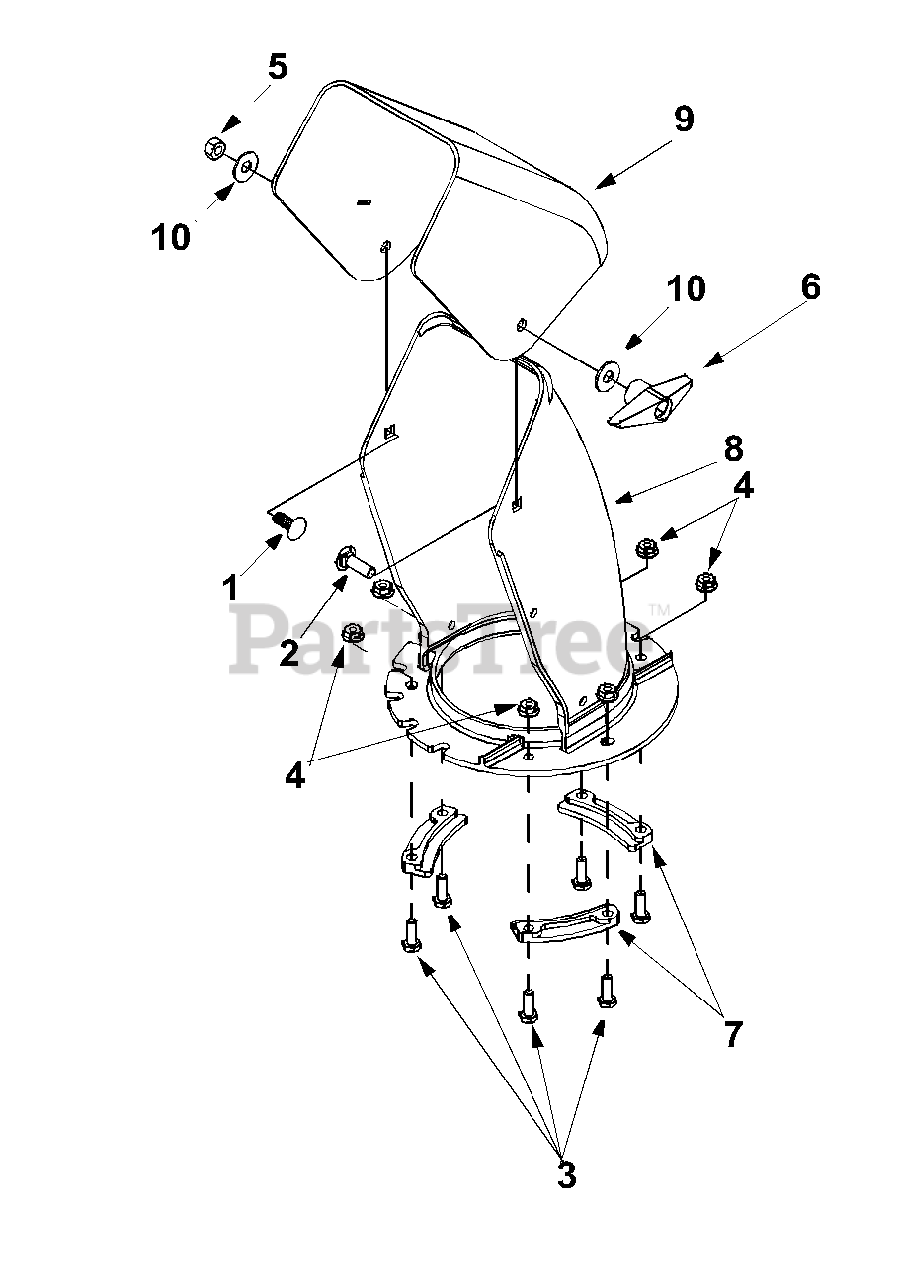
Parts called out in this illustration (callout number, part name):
1	Carriage Screw: Special
2	Carr. Bolt 5/16-18 x 0.750"
3	Hex Screw 1/4-20 x 0.75"
4	Lock Nut
5	Hex Lock Nut
7	Flange Keeper: Chute
8	Lower Chute
9	Upper Chute
